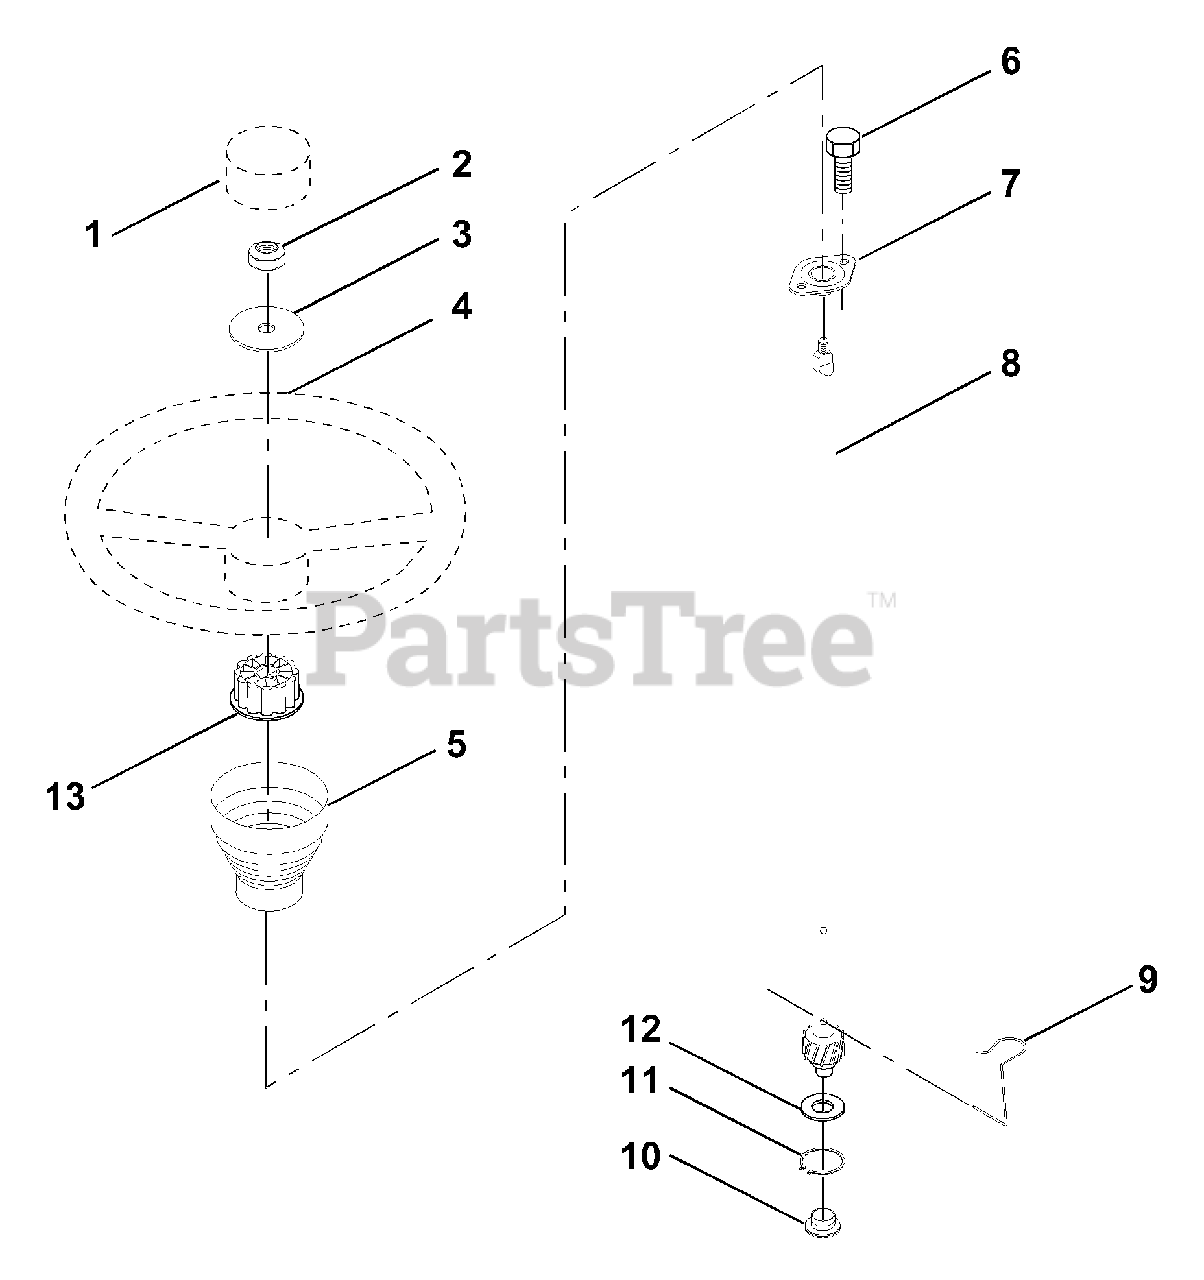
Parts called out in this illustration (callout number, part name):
1	Insert, Wheel, Steering
2	Nut, Lock 3/8-24 UNF
3	Washer 12/32 x 2-3/8 x 8 Ga.
4	Wheel, Steering
5	Sleeve, Steering
6	Screw, Hex #10-16 x 1/2 TY-B
7	Bushing, Steering
8	Shaft, Steering
9	Clip, Steering
10	Bushing, Lower, Steering
11	Ring, Retaining
12	Washer 21/32 x 1 x 16 Ga.
13	Adaptor, Wheel, Steering
